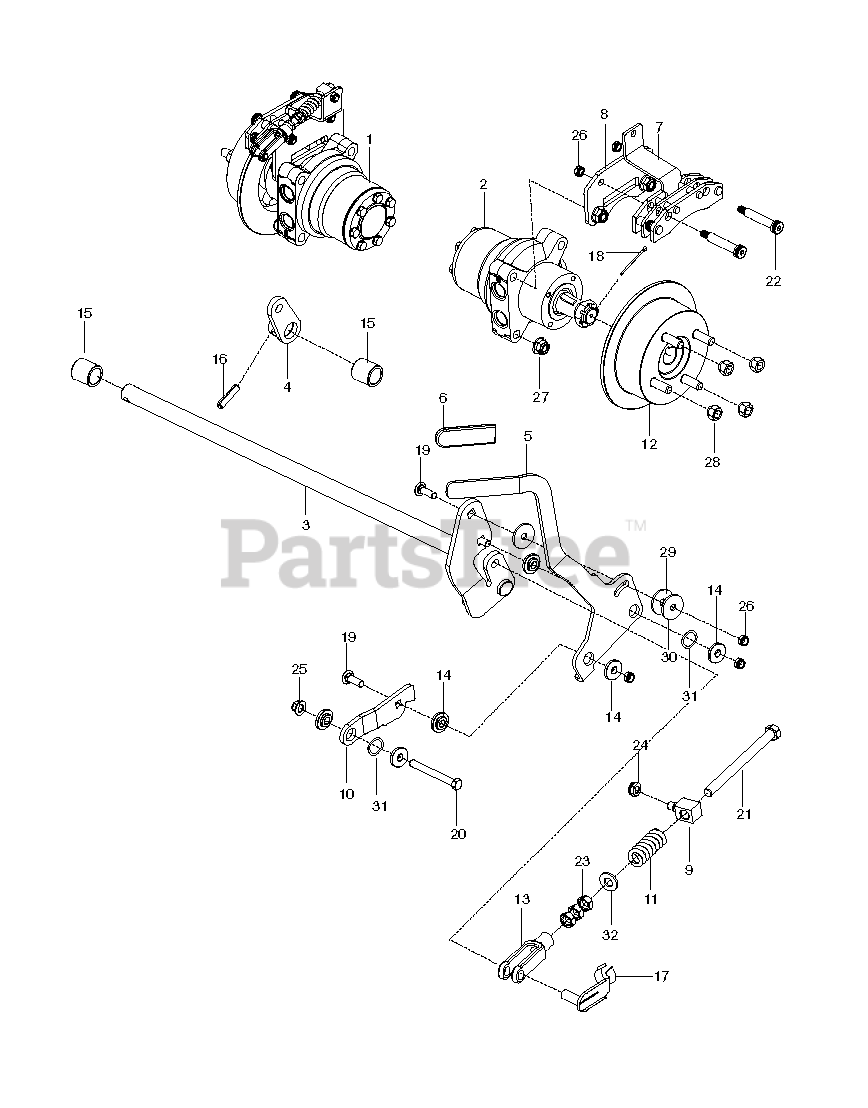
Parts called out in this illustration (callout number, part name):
1	MOTOR, TL0310, RT
2	MOTOR, TL0310, LT
3	SHAFT, BRAKE WLDMT
4	ARM, RT BRAKE
5	LEVER.BRAKE.BLACK
8	PLATE, CALIPER
9	SWIVEL, BRAKE
10	LINK, FOLLOWER
12	HUB, DISC BRAKE, W/STUDS
13	YOKE-3/8-24 PLTD
14	BUSHING, BRAKE
15	BUSHING, SLEEVE 3/4 X 1.0
16	5/16 DIA ROLL PIN
17	PIN, CLEVIS SPRING, 3/8
18	COTTER PIN 1/8 X 2
19	RHSNB 3/8-16 X 1-1/4
20	HCS 3/8-16 X 3-1/4 GR5 ZD
21	HCS 3/8F X SPECIAL
22	BOLT, SHOULDER, 1/2 X 2.25
23	NUT 3/8-24 JAM
24	5/16-18 THIN PROF NY
25	NUT 3/8-16 HEX FLG NYLOC ZD
26	NUT HEX 3/8-16 NYLON, THIN
27	NUT, 1/2-13 HEX FLG NYLOC ZD
28	LUG NUT 1/2F
29	WASHER, FRICTION, 1/8
30	CONE WASHER
31	WASHER, .825 X 1.087, WAVE
32	WASHER 3/8 SAE FLAT
